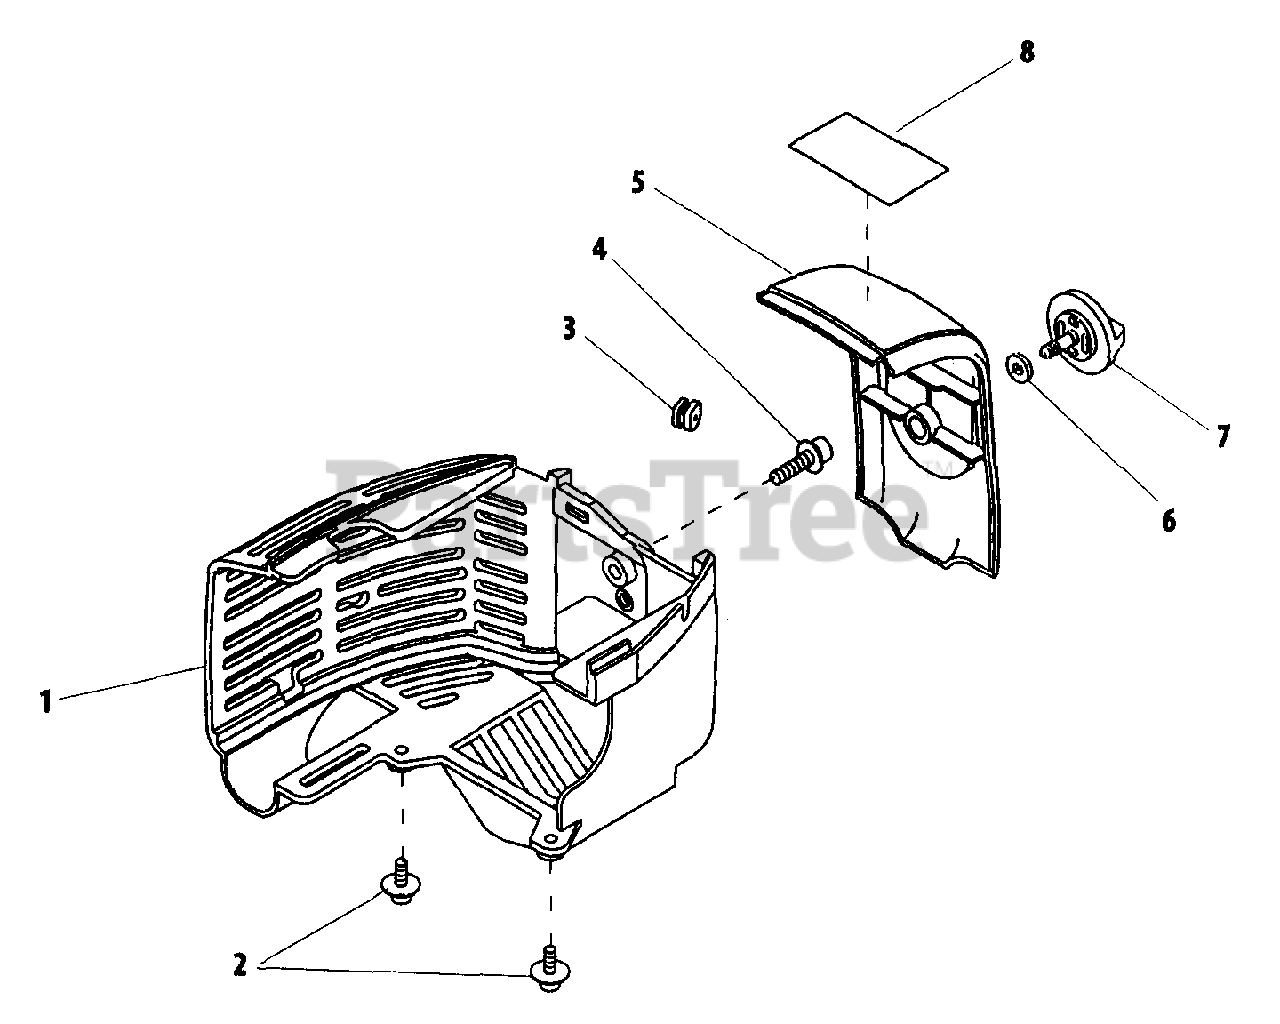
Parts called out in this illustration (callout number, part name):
1	COVER, ENGINE
2	BOLT
3	GROMMET, LEAD
4	BOLT, ADHESIVE M5×20
5	COVER
6	WASHER 5
7	THUMBSCREW
8	LABEL - TRADE
